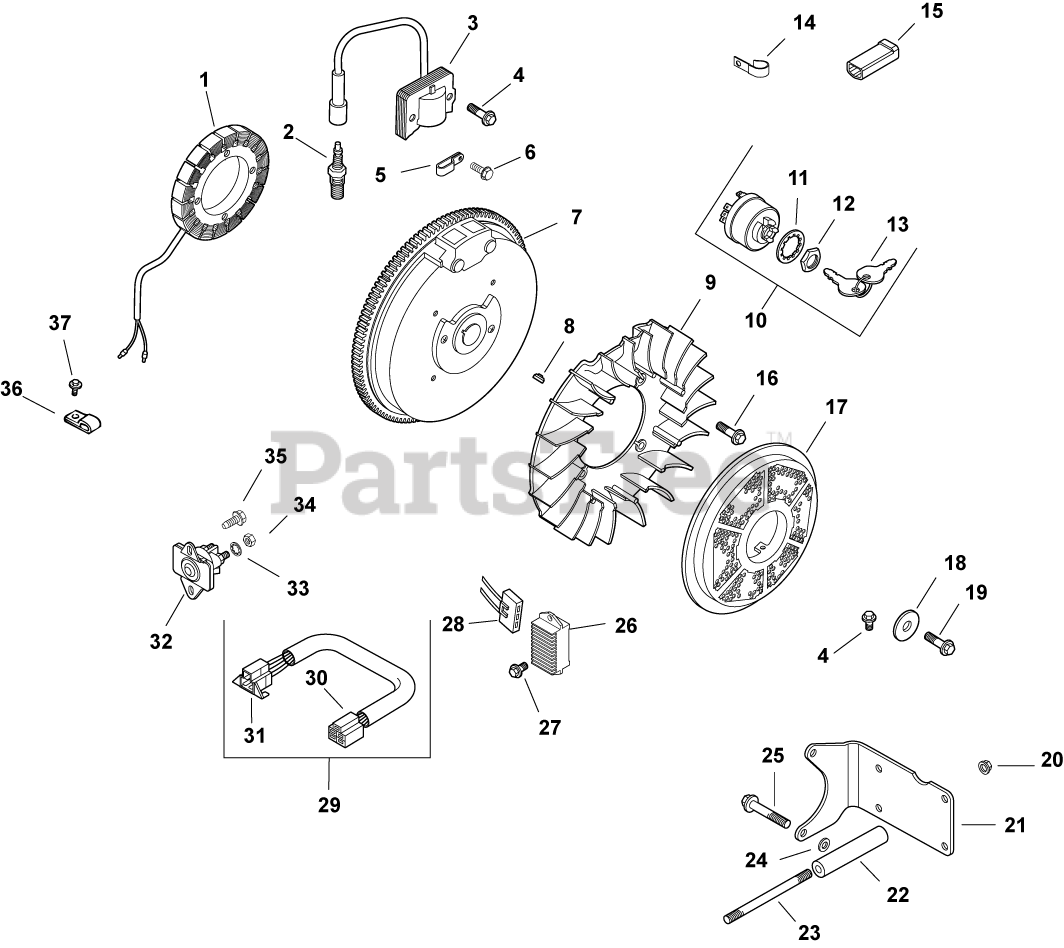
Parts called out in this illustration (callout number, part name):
1	KIT, 15 / 20 AMP STATOR
2	PLUG, SPARK (STD)
3	MODULE, IGNITION
4	SCREW, FLG THD FRM M5X.8X20-(#25086399S)
6	SCREW, FLG THD FRM M5X.8X10
7	FLYWHEEL ASSY PAINTED - USE 12 025 74-S
8	KEY, 3/16" X 5/8"
9	FAN - DISCONTINUED
10	SWITCH ASSY, KEY (KM)-USE 25 099 32-S
11	WASHER, INTERNAL TOOTH
12	NUT, KEY SWITCH
13	KEY, SET -USE 48 340 01-S
14	CLIP, CABLE
15	CONNECTOR (1 CONTACT)
16	BOLT, SHOULDER
18	WASHER, FLAT 13/32"
19	SCREW, FLG M10X1.5X45 - (#25086361S)
20	NUT, FLG M8X1.25
21	BRACKET, FUEL TANK
23	STUD, M8X1.25X133-USE 25 755 54-S
24	WASHER, FLAT 11/32"
25	SCREW, FLG M8X1.25X50
26	REG/RECT-15 AMP (KM)-USE 41 403 10-S
27	SCREW, FLG M6X1.0X16
28	CONNECTOR ASSEMBLY
29	CONNECTOR
30	CONNECTOR
31	CONNECTOR, BODY (KM)-USE 25 155 41-S
32	SOLENOID - WATERPROOF (KM)-USE 25 435 08
33	WASHER, INT TOOTH LOCK 1/4"
34	NUT, JAM 1/4-20 GRADE 2
35	SCREW,FLG THD FRM M6X1.0X16-(#25086397S)
36	CLIP, TUBE & WIRING (KM)
37	SCREW, M5X0.8X25 - (#25086402S)
1251809-S	LEAD, STARTER SOLENOID - DISCONTINUED
2551829-S	LEAD, GROUND SOLENOID
